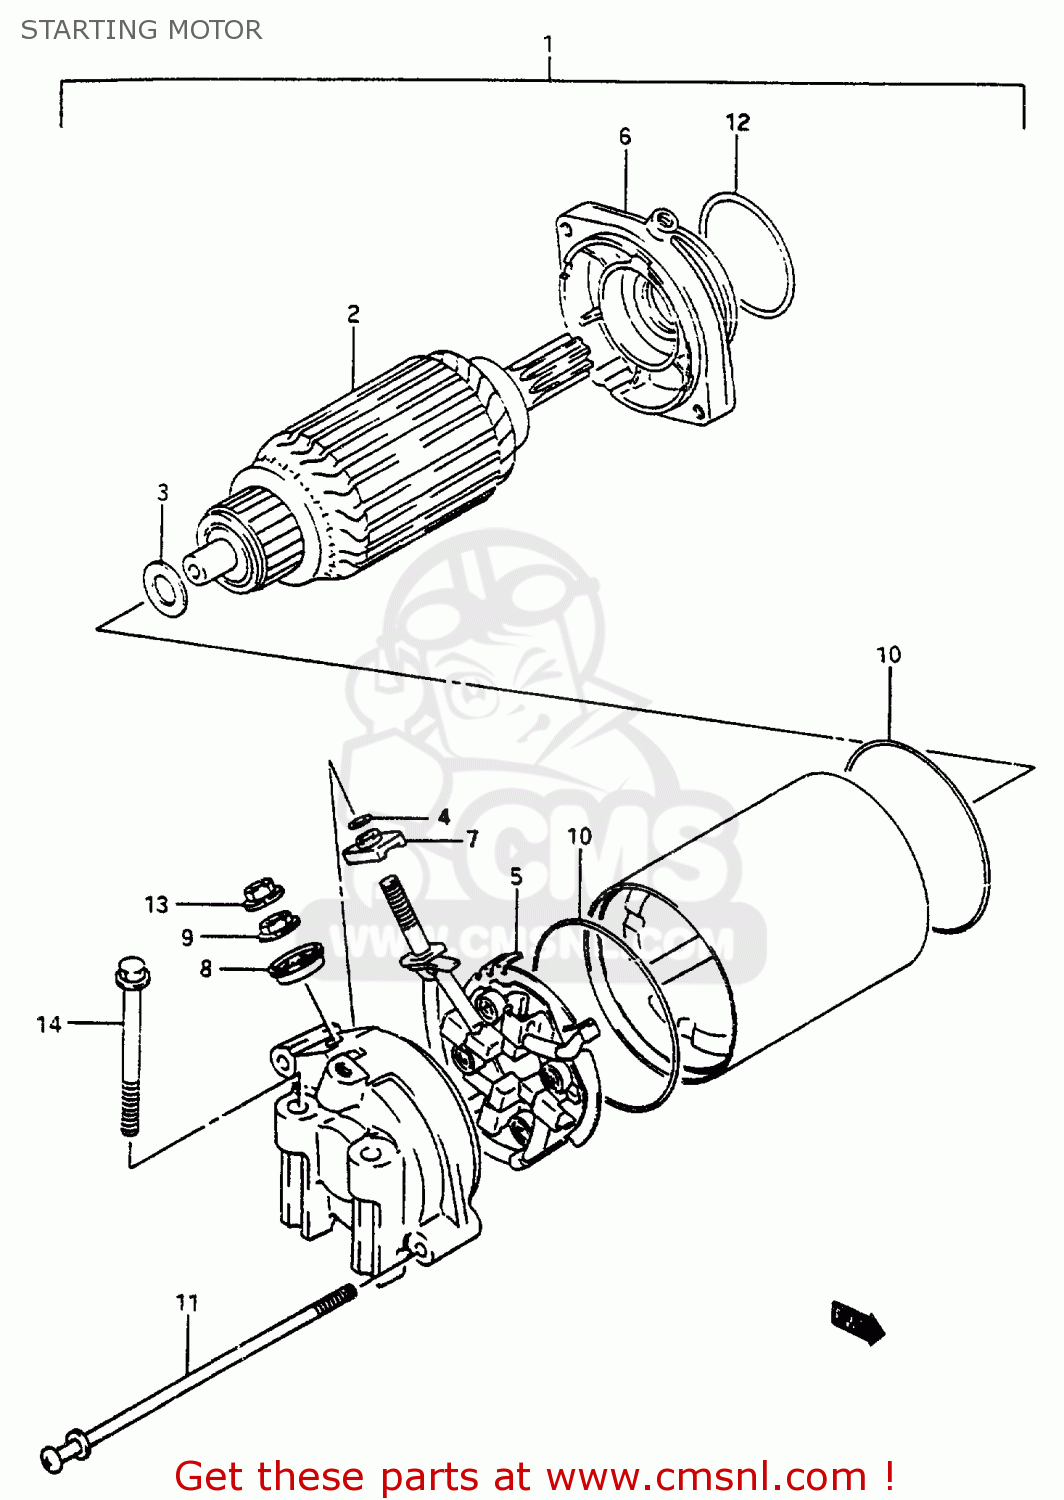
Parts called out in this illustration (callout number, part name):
1	MOTOR ASSY,STARTING
2	ARMATURE
3	SHIM SET,STARTING MOTOR
4	O RING
5	HOLDER SET,BRUSH
6	BRACKET SET
7	BUSHING
8	BUSHING
9	NUT
10	O RING
11	BOLT
12	O RING
13	NUT
14	BOLT
